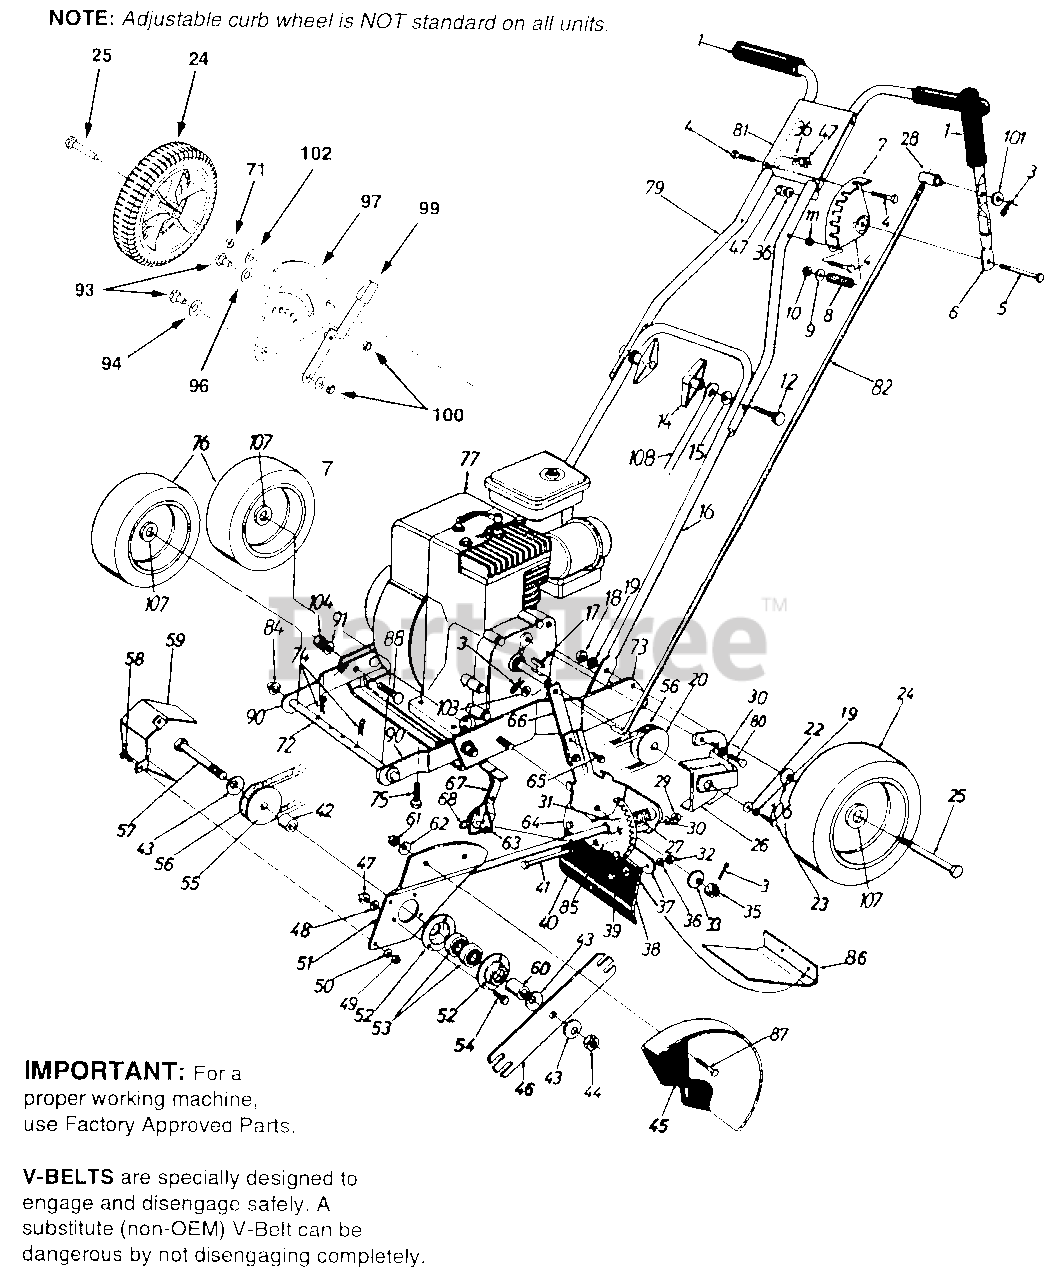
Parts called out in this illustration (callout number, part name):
3	Cotter Pin 5/16" Dia.
4	Hex Bolt 1/4-20 x 1.25" Lg.
5	Hex Bolt 5/16-18 x 2" Lg.
8	Compression Spring 1.38" Lg.
9	Flat Wash. .344" I.D.
10	Hex L-Nut 5/16-18 Thd.
12	Curv. Hd. Bolt 5/16-18 x 2" Lg.
14	Wing Nut Ass'y.
15	Saddle Wash. .32" I.D. x .937"
18	Hex Nut 3/8-16 Thd.
19	L-Wash. 3/8" I.D.
20	Engine Pulley
22	Flat Wash. .385" I.D.
23	Hex Bolt 3/8-24 x 1 Lg.
24	Wheel, Slot Bar Gray
25	Shoulder Bolt .498" Dia.
28	Ferrule
29	Hex Nut 5/16-18 Thd.
30	L-Wash. 5/16" I.D.
31	Spring Pin Spir. 1/4" Dia.
32	Hex Nut 1/4-20 Thd.
33	Bell Wash. .535" I.D.
35	Hex Slotted Nut 1/2-20 Thd.
36	L-Wash. 1/4" I.D.
39	Hex Bolt 1/4-20 x .62" Lg.
41	Hex Bolt 5/16-18 x 4.5" Lg.
42	Spacer 1.030" Lg.
43	Bell Washer .63" I.D.
44	Hex Jam L-Nut 5/8-18 Thd.
47	Hex Nut 1/4-20 Thd.
48	L-Wash. 1/4" I.D.
49	Hex Nut 1/4-20 Thd.
50	L-Wash. 1/4" I.D.
53	Ball Bearing .62 I.D.
54	Hex Bolt 1/4-20 x .62" Lg.
55	3/8" "V"-Pulley
56	"V"-Belt
57	Hex Bolt 5/8-18 x 4.5" Lg.
58	Hex Bolt 1/4-20 x .625" Lg.
60	Sleeve .90" Lg.
61	Hex Nut 5/16-18 Thd.
62	Bell Wash. .345" I.D.
63	Spring Pin Spir. 1/4" Dia.
68	Torsion Spring
71	Spacer
72	Axle 8.20" Lg. (Front)
75	Hex TT-Tap Scr. 3/8-16 x 1" Lg.
76	Wheel, Slot Bar Gray
77	Engine
84	Push Cap 1/2" Dia.
85	Spacer 3.765" Lg.
88	Ribbed Neck Bolt 3/8-24 x .8" Lg.
93	Shld. Bolt .5" Dia.
94	Bell Wash. .515" I.D.
96	Flat Wash. .51" I.D. x 1.0" O.D.
100	Hex Jam Nut 3/8-16 Thd.
101	Flat Wash. .344" I.D. x .62" O.D.
102	Wave Wash. .51" I.D.
103	Flat Washer .406" I.D. x .81" O.D.
104	Hex Nut 3/8-24 Thd.
106	Bell Washer .38" I.D. x .88" O.D.
